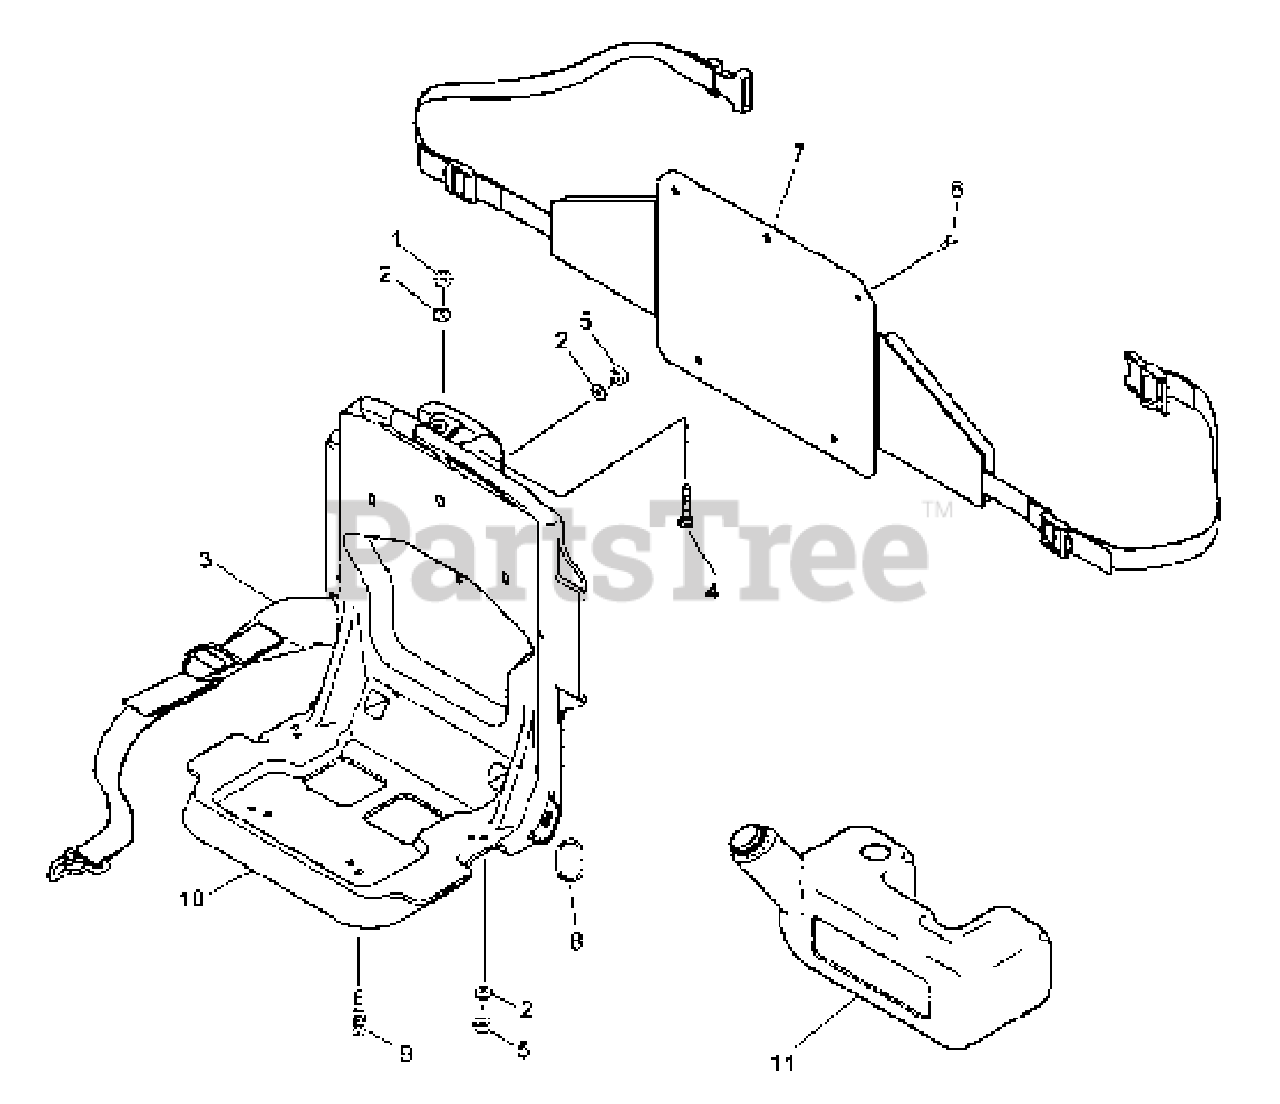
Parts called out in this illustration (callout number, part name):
1	Flange Nylon Nut
2	Washer
3	Shoulder Band
4	Truss Screw
6	Clip
7	Knapsack Pad
10	Knapsack Frame
11	Fuel Tank
